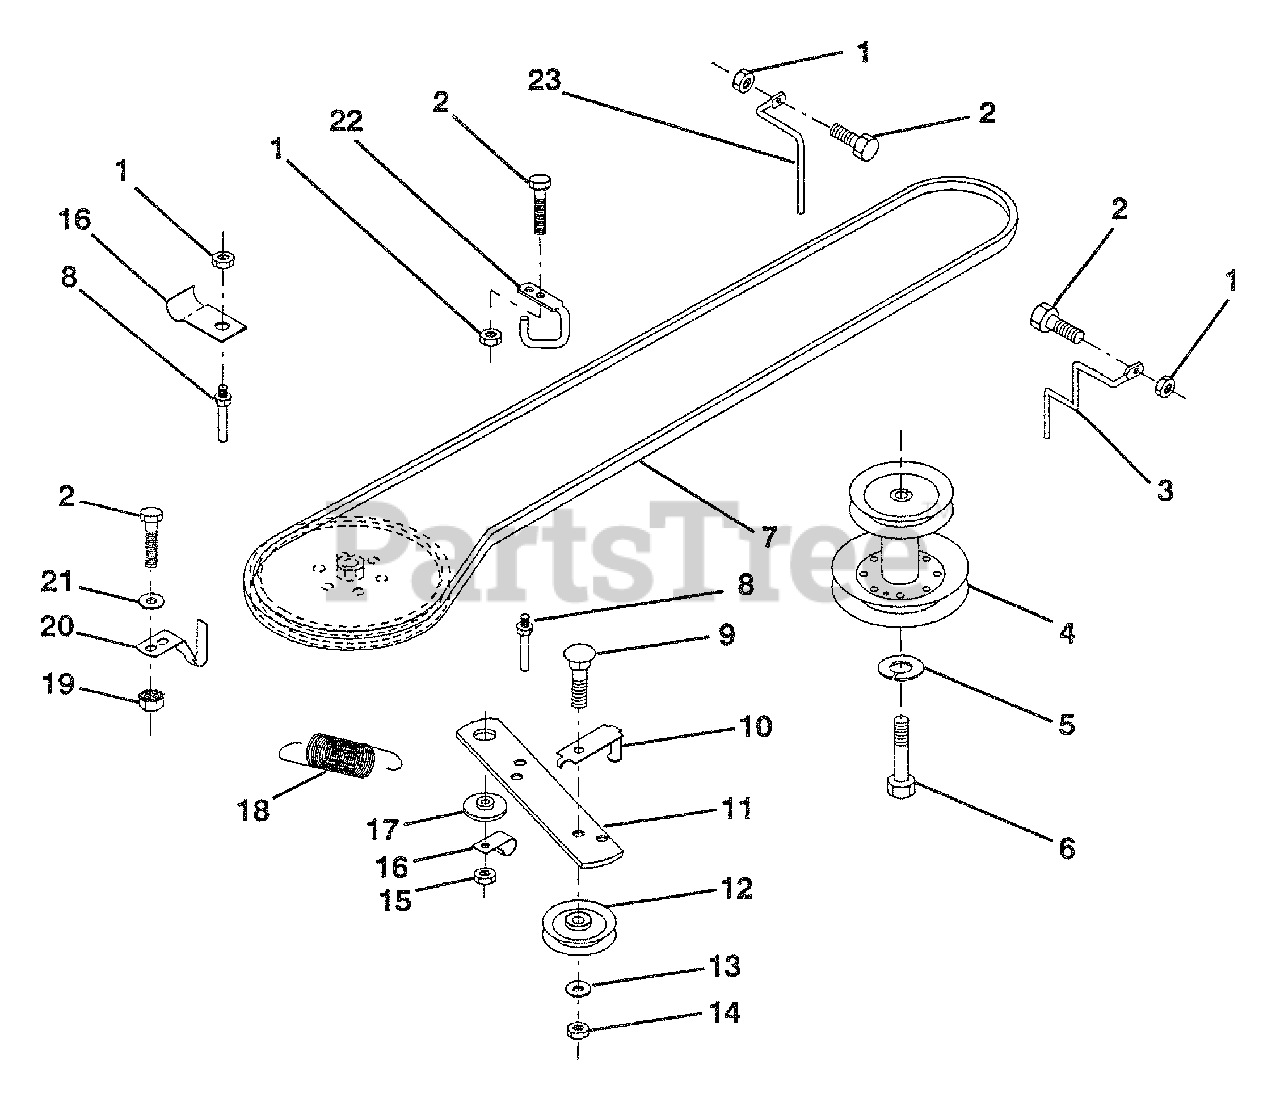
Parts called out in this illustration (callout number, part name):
1	Nut, Crownlock 5/16-18
2	Bolt, Hex Hd 5/16-18 UNC x 3/4
3	Keeper,Mower Drive, R.H.
4	Pulley, Engine
5	Washer, Lock 7/16
6	Bolt Hex 7/16-20 Gr. 5
7	Traction, V-Belt Drive
8	Keeper, T/A Ground Drive Belt
9	Bolt, Carr. 3/8-16 UNC x 1-1/2
10	Keeper, Belt Ground Drive Idler
11	Arm, Ground Drive Clutch
12	Idler, Flat
13	Washer 13/32 x 13/16 x 16 Ga.
14	Nut, Centerlock 3/8-16 UNC
15	Nut, Crownlock 3/8-16 UNC
16	Clip, Insulated
17	Spacer, Retainer
18	Spring Extension
19	Nut, Keps 5/16-18 UNC
20	Keeper, T/A Ground Drive Belt
21	Washer 11/32 x 5/8 x 16 Ga.
22	Keeper, Frame Ground Drive Belt
23	Keeper, Mower Drive, L.H.
